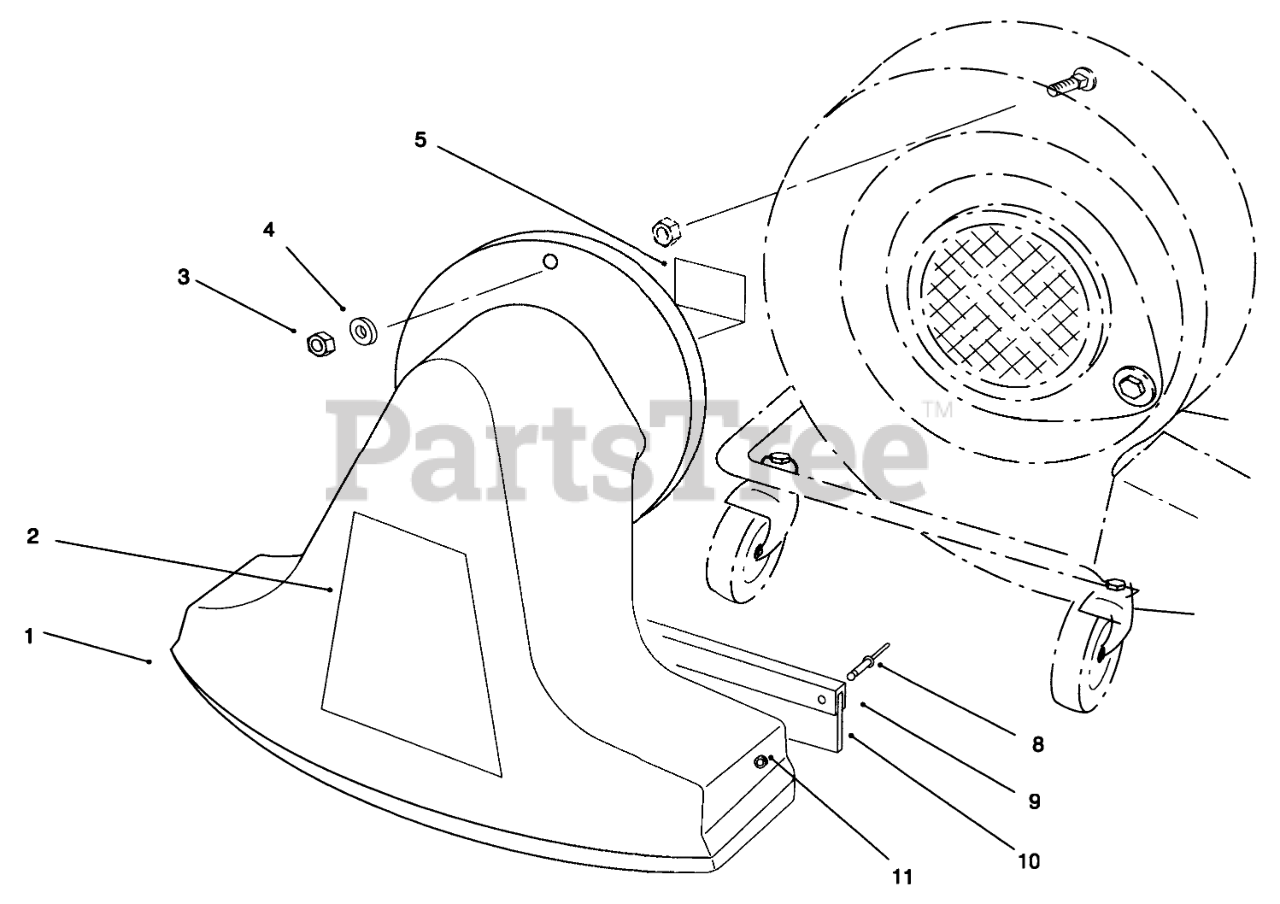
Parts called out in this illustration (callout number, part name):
1	Snout Assembly (Incl. Ref. #1, 8-10)
2	DECAL-VACUUM SP
3	NUT-LOCK, NI
4	Washer
5	DECAL-CAUTION, BAG
8	POP RIVET 3/16X.375LG
9	Clamp-Flap
10	FLAP-RUBBER
11	WASHER-FLAT
